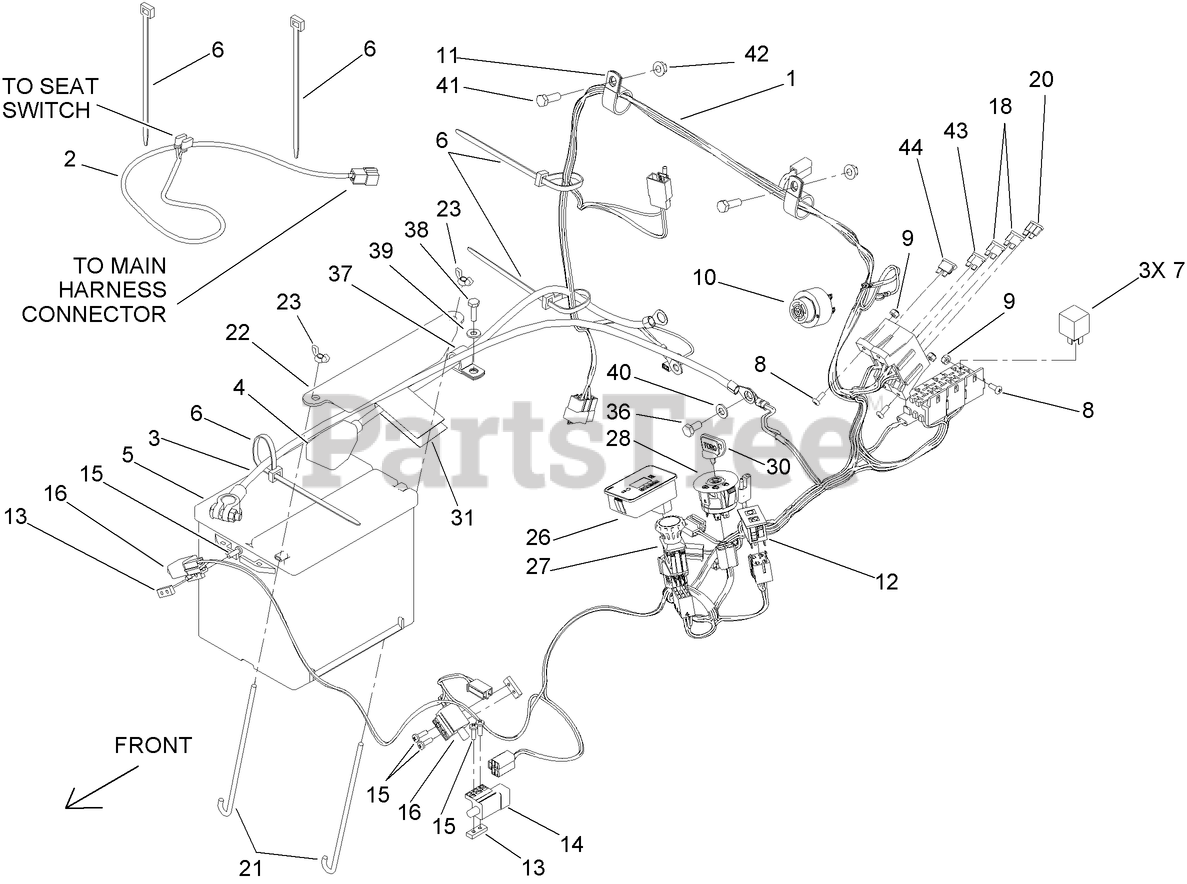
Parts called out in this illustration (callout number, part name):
1	HARNESS-WIRE
2	HARNESS-WIRING, SEAT
3	CABLE-BATTERY, NEGATIVE
4	CABLE-BATTERY, POSITIVE
5	BATTERY-DRY
6	TIE-PLASTIC
9	NUT-LOCK, NI
10	ALARM-TONE, DUAL
11	CLIP-LOOM
12	LAMP-WARNING
13	PLATE-TAPPED
14	SWITCH
15	SCREW-PPH
16	SWITCH-OPEN, NORMALLY
18	FUSE-BLADE, 10 AMP
20	FUSE-BLADE, 30 AMP
21	Bolt-Holddown
22	HOLDDOWN-BATTERY
23	WINGNUT
26	HOUR METER ASM
27	SWITCH-PTO, 10 AMP
28	SWITCH-IGNITION
30	KEY-IGNITION
31	DECAL-INSTRUCTIONS, CHARGING
36	SCREW-HH
37	CLIP-LOOM
38	SCREW-HH
39	WASHER-FLAT
40	WASHER-PLAIN
41	SCREW-HH
42	NUT-HF
43	FUSE-40 AMP
44	FUSE-BLADE, 15 AMP
